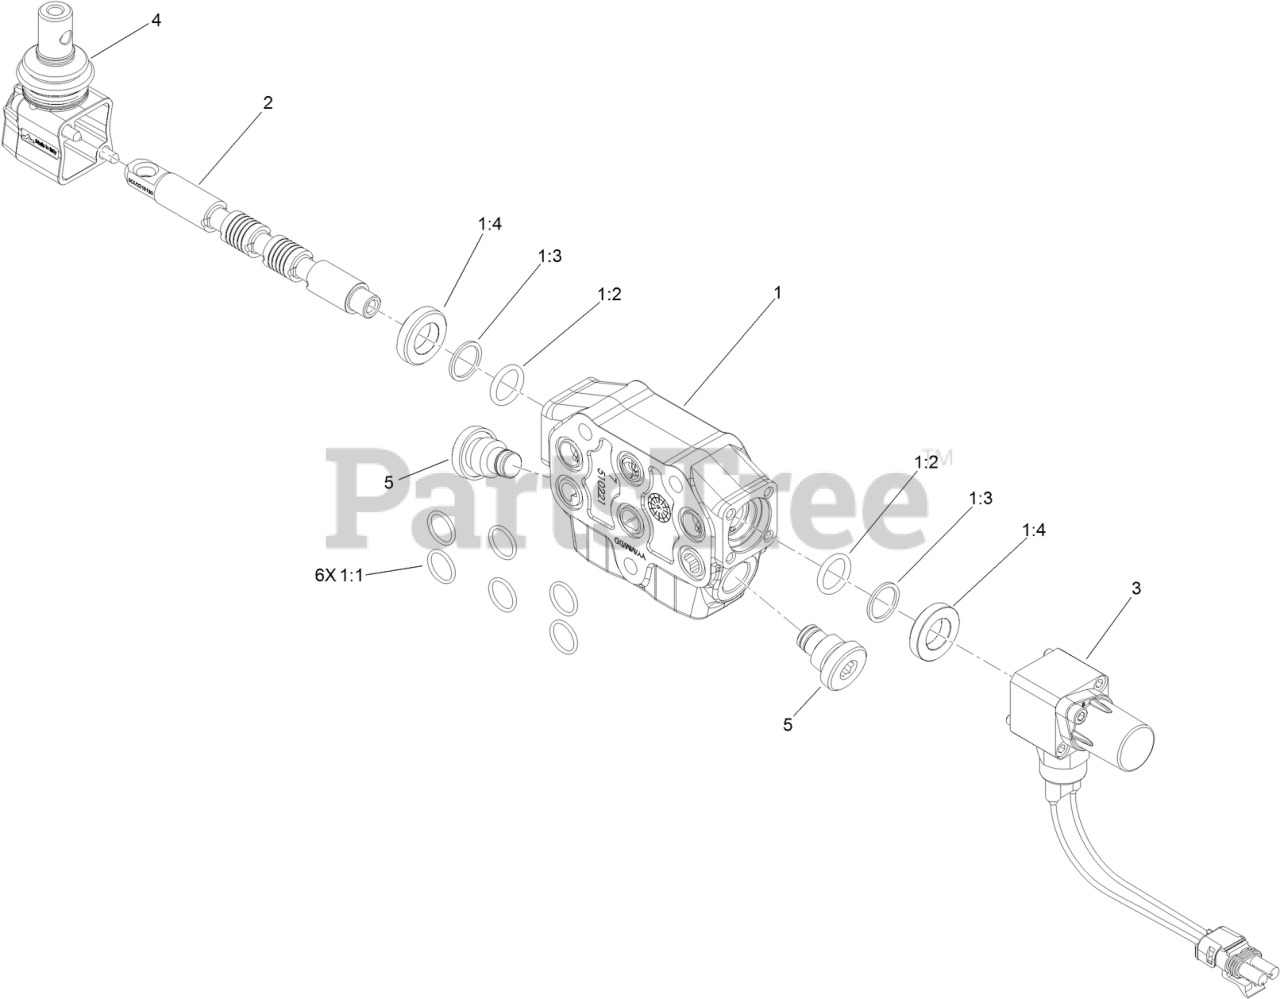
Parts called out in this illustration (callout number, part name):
1	SECTION-WORKING
1:1	O-RING
1:2	SEAL-VALVE
1:3	SEAL-VALVE
1:4	SEAL-VALVE
2	VALVE-SPOOL
3	KIT-CONTROL
4	LEVER-VALVE
